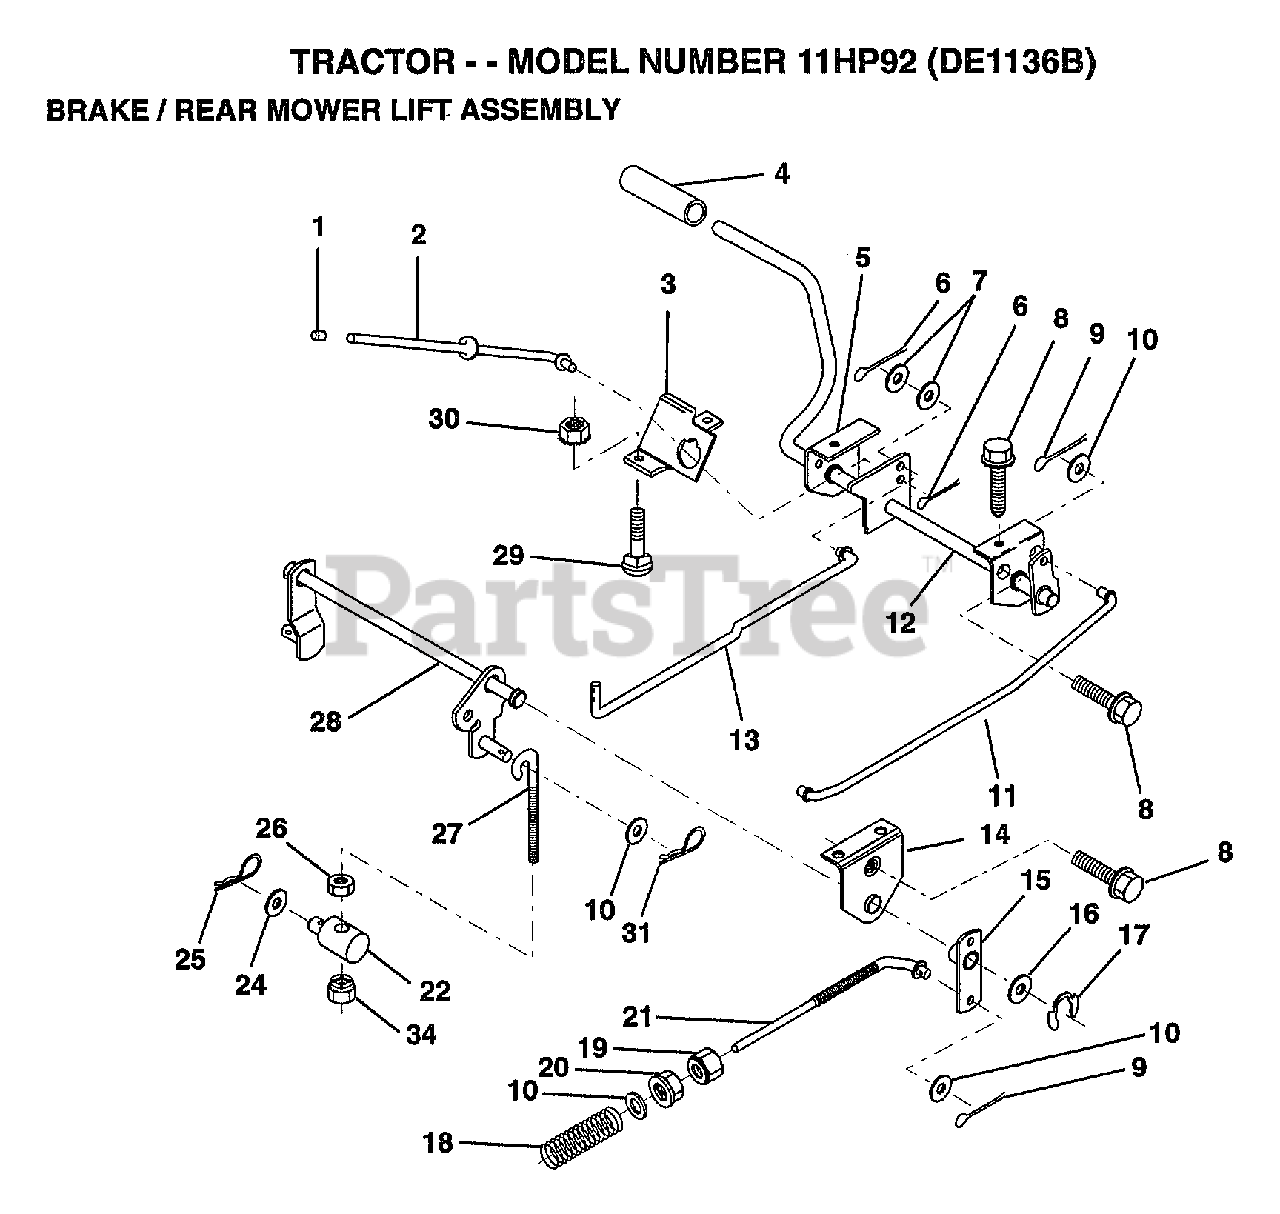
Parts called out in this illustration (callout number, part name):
1	PLUNGER CAP T
2	"ROD,PARK BRAKE"
3	"BRKT,PARK BRAKE"
4	FOOT PEDAL COVER
5	"BRKT,CLU PEDAL LH"
7	WASHER
8	SCREW LT
9	COTTER PIN
10	WASHER
11	"ROD,FRT BRAKE"
12	PEDAL ASM CL/BK36
13	"ROD,CLUTCH"
14	"BRKT,LIFT SHAFT"
15	PVT BRAKE ARM ASM
16	WASHER T
17	KLIP RING
18	SPRING ROD BRAKE
19	NUT
20	NUT
22	TRUNNION.LIFT.
24	WASHER
25	SPRING.RETAINER
26	LOCKNUT
27	"LINK, MOWER REAR"
28	LIFT ASM MOW REAR
31	RETAINER.SPRING
